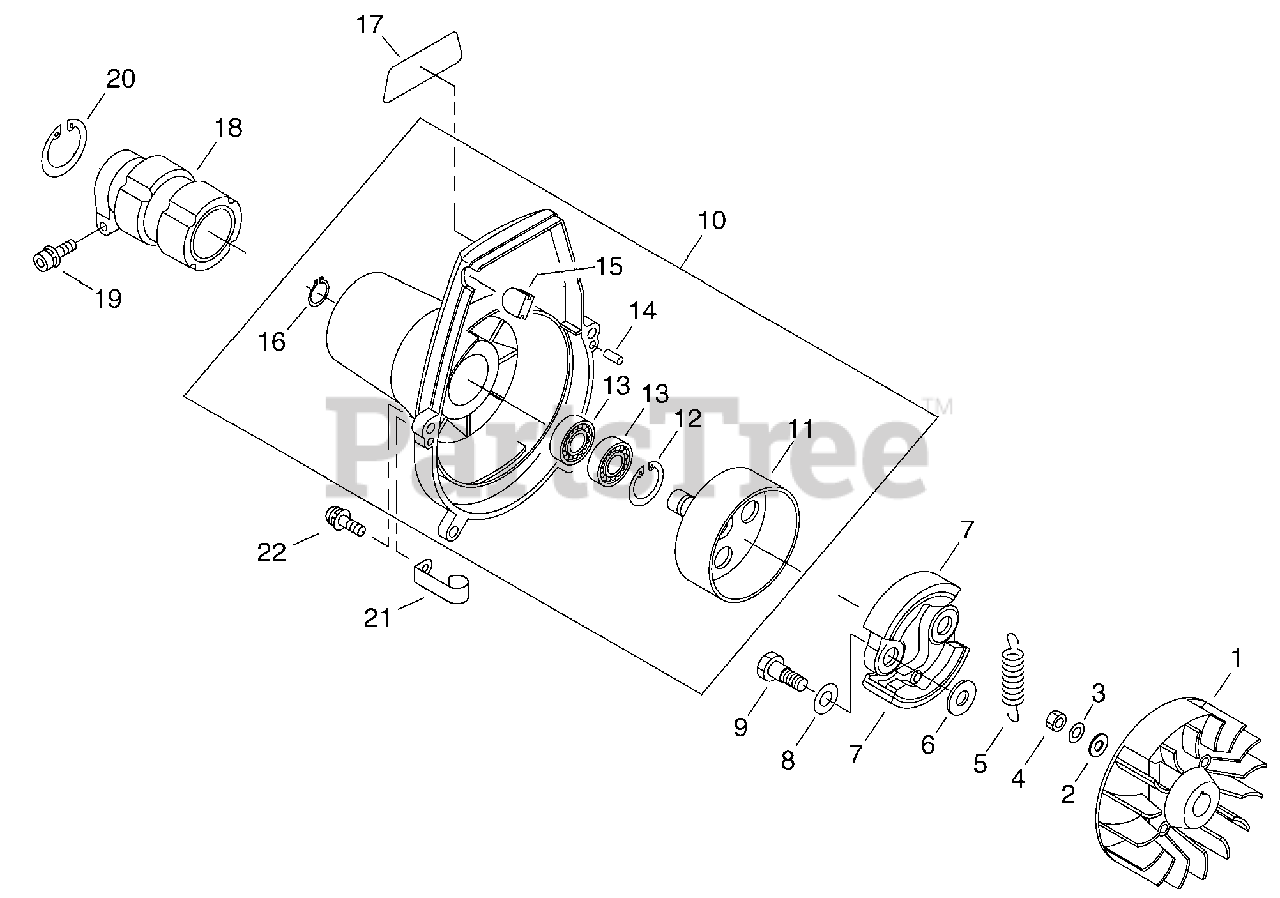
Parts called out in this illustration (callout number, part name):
1	FLYWHEEL
2	WASHER 8.5×16×1.2
3	WASHER, SPRING 8
4	NUT 8×1.25
5	SPRING, CLUTCH
6	WASHER 6.2×19×1.0
7	SHOE, CLUTCH
8	WASHER, SPRING 8.5×16×0.5
9	BOLT, CLUTCH 8×7.9×M6
10	COVER ASSY, FAN
11	DRUM, CLUTCH
12	RING, SNAP 26
13	BEARING, BALL 6000LU
14	PIN, LOCATING 4×8
15	GROMMET, PLUG
16	E-RING 10
17	LABEL - MODEL SRM-270
18	HOLDER, MAIN PIPE
19	BOLT 5×28
20	RING, SNAP Ø42
22	SCREW 5×18
